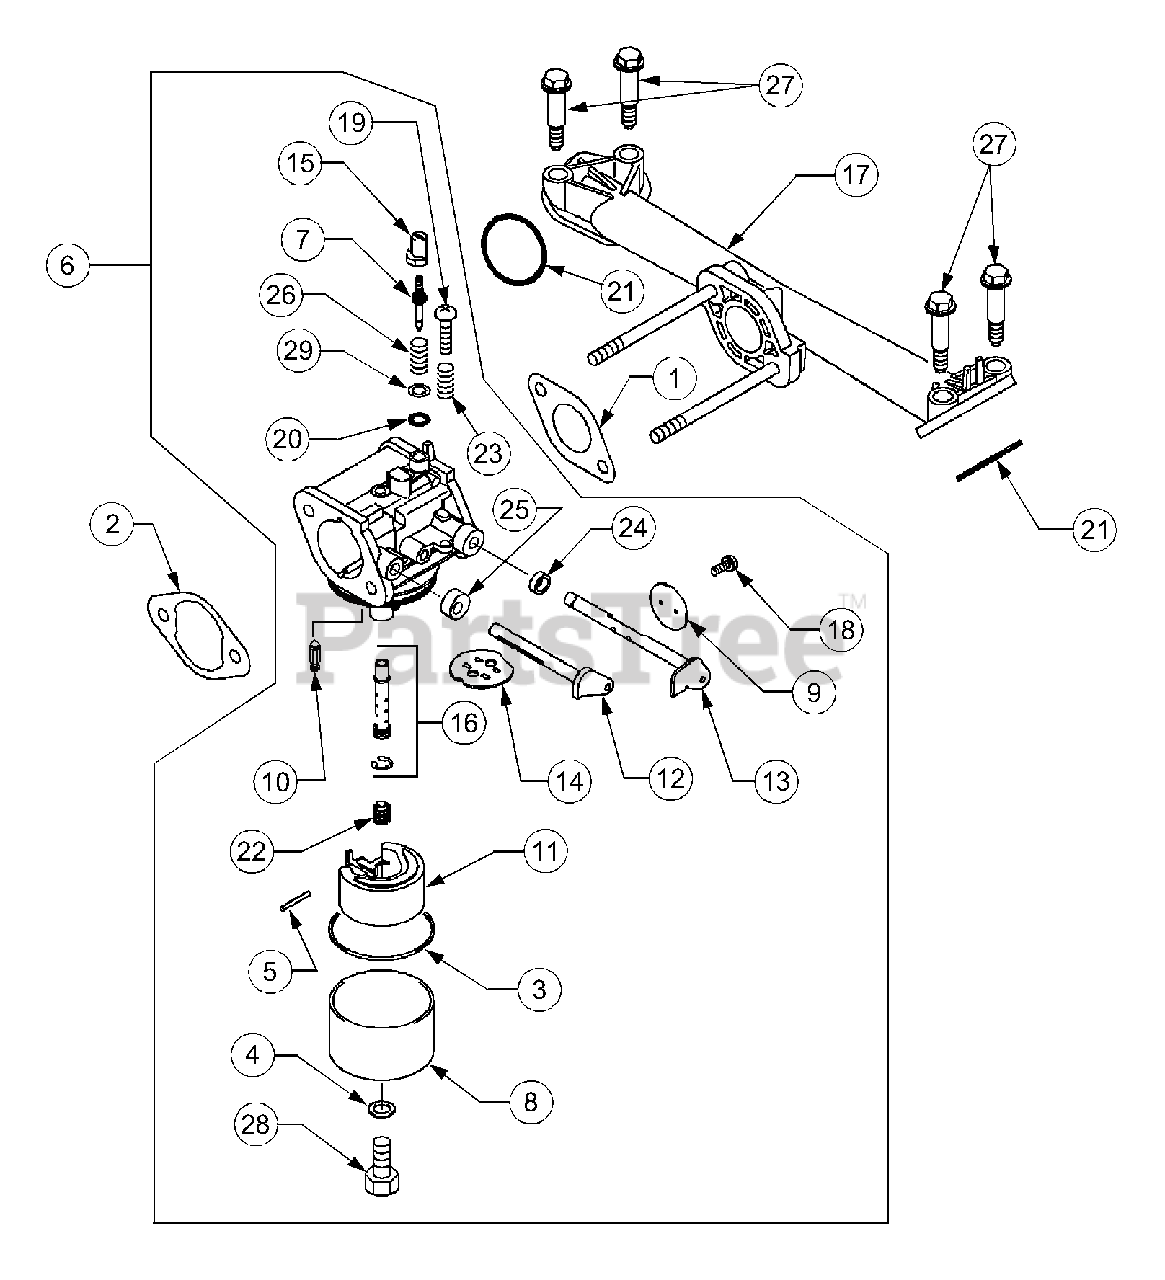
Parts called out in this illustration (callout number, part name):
1	Gasket, Manifold - Carb
2	Gasket, Carb
3	Gasket, Chamber
6	Carburetor Assy
7	Screw, Pilot Air
8	Chamber, Float
9	Valve, Throttle
12	Shaft, Carburetor Choke
13	Shaft, Carburetor Throttle
14	Valve Assy, Choke
17	Manifold, Intake
21	O-Ring, Id=31
22	Jet, Main, #88
28	Screw
